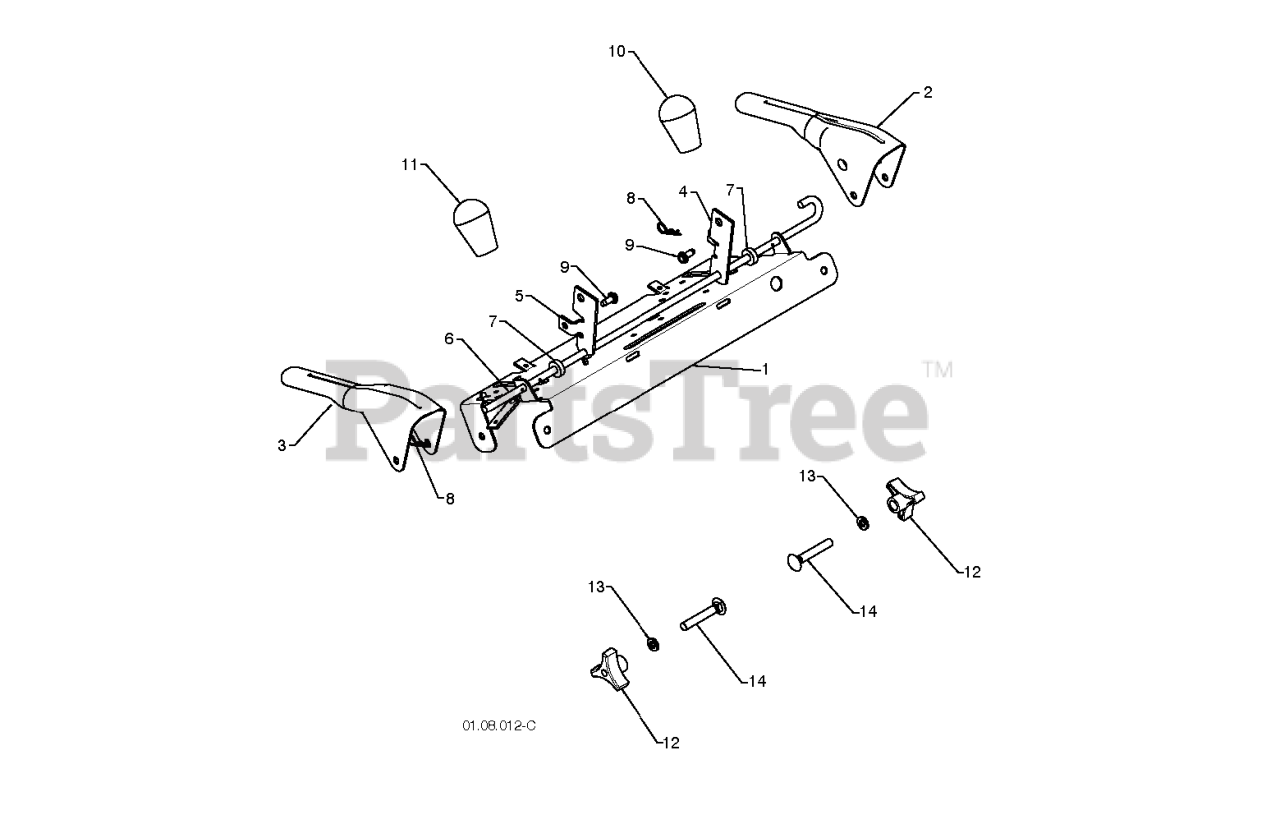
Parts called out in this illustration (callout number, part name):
1	STOP.INTERTLOCK
2	LEVER.CONTROL.LH.BLACK
3	LEVER.CONTROL.RH.GREY
4	ARM.TRACTION.ROD.YZ
5	ARM.IMPELLER.ROD.SNOW
6	BAIL.CONTROL.INTERLOCK
7	SPACER.CONTROL.LEVER
8	SPRING RETAINER
9	SCREW 14-20 X 5/8
10	KNOB LEVER, BLACK
11	RED KNOB SHIFTER
12	KNOB.HANDLE.3/8.TRI-POINT.BLAC
13	WASHER
14	BOLT 3/8-16 X 2-1/4
